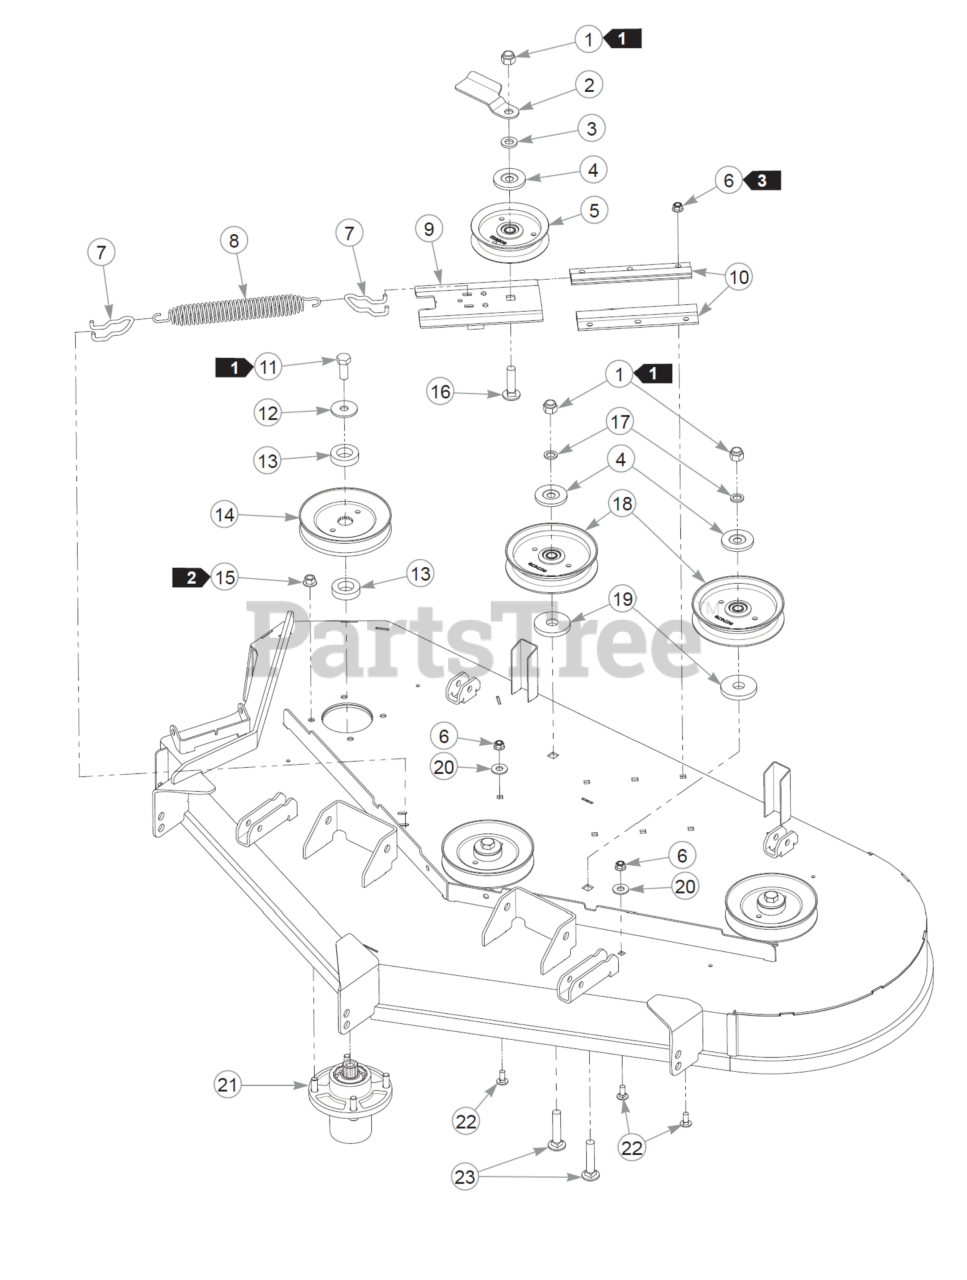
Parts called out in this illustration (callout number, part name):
1	NT .500-13NLG5
2	BELT GUIDE
3	FW 0.531 X 0.90 X 0.134
4	DUST SHIELD
5	4" IDLER PULLEY
6	NT 0.312-18 FL NY G5
7	ANCHOR, SPRING TENSIONER
8	SPRING, DECK IDLER
9	SLED, IDLER
10	IDLER SLIDE, EXTRUDED
11	CS .500-13X1.25 HX G5 ZN
12	FW .515X1.65X.12 HD ZN
13	SPACER, SPINDLE PULLEY
14	PULLEY, DECK DRIVE B-SEC
15	NT .375-16 FL NY GF
16	CB .50-13 X 2.00 STD ZN
17	FW .531X.812X.089 HD
18	IDLER PULLEY, 5.00"
19	FW .73X2.25X.31 ZN
20	FW .440X1.00X0.08 ZN
21	BLADE SPINDLE ASSY
22	CB .312-18X .750 FUL ZN
23	CB .50-13 X 2.50 STD ZN
